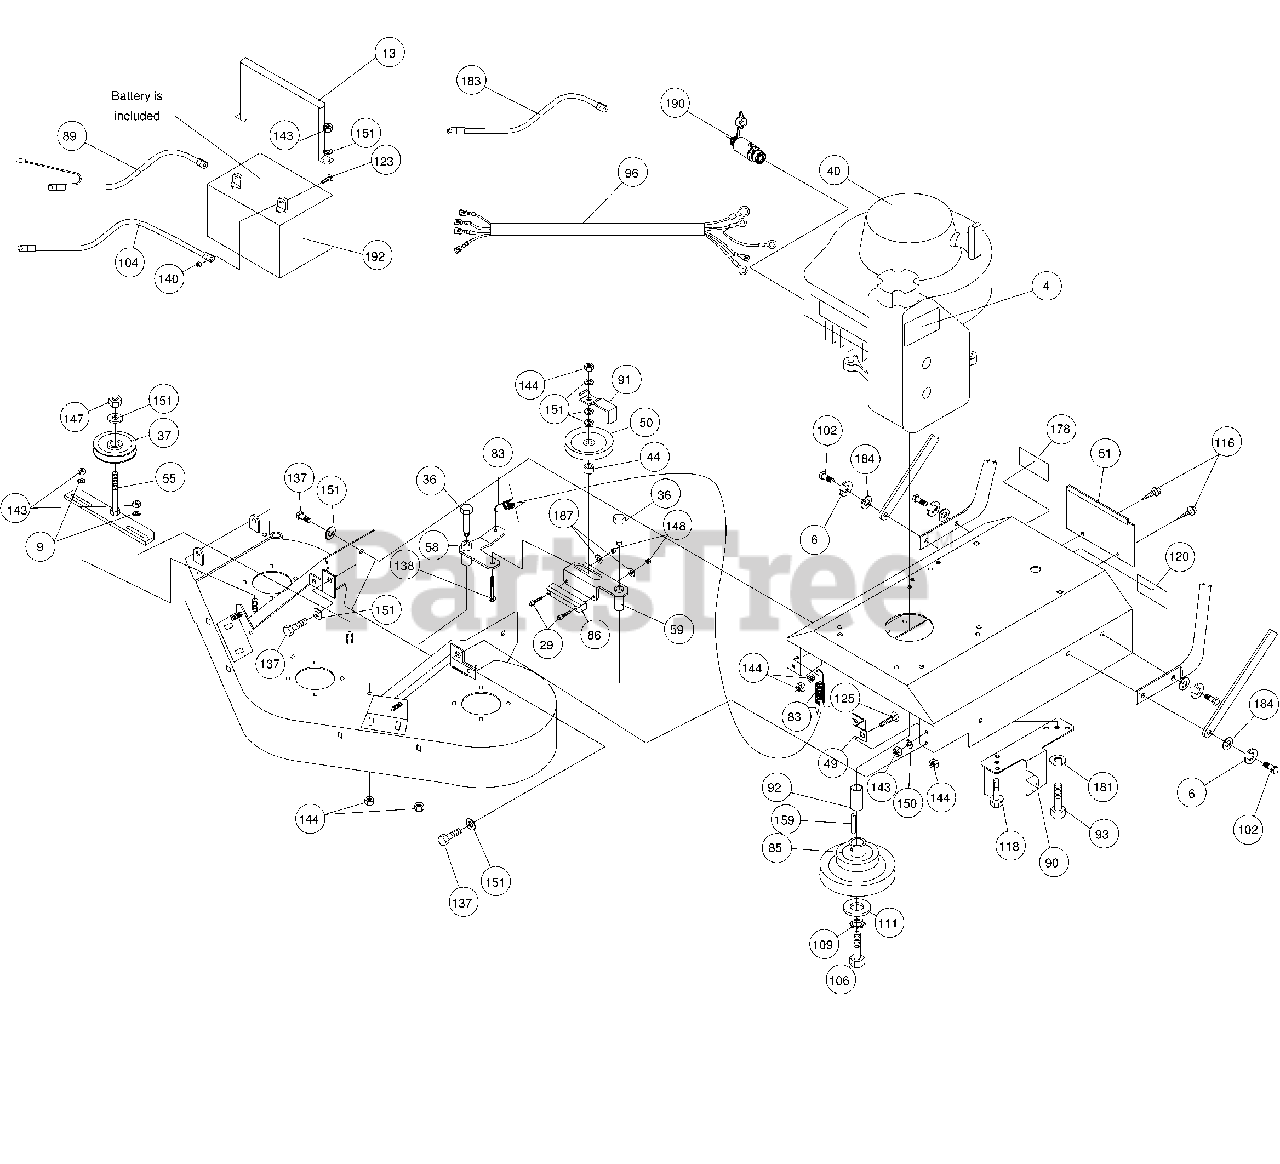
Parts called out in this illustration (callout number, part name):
4	LABEL HOT ENGINE
6	WASHER SPLIT LOCK 3/8"
9	WASHER 5/16" TWISTED LK.
13	BATTERY BRACKET
29	SCREW SOCKET #10 X 1”
36	BOLT SHOULDER 1/2” X 2”
37	IDLER PLASTIC 4” X 0.375
40	ENGINE 13 HP B&S
44	SPACER NYLON BRAKE
49	BRKT CLUTCH CABLE FM
50	PULLEY IDLER BLADE DRIVE
51	PLATE ACCESS DOOR FM
55	BRKT IDLER DECK BLADE WA
58	PLATE BLADE CLUTCH IDL.
59	PLATE BLADE CLUTCH BK
83	SPRING TENSION WIRE
85	PULLEY DOUBLE 6 / 3.5 FM
86	BRAKE PUCK FM
89	CABLE BATTERY POS 10”
90	BRACKET BELT FINGER
91	BRACKET BELT FINGER BK.
92	SPACER HUB 1” BORE 1.5”
93	SCREWCAP 5/16” -18 x 2"
96	WIRE HARNESS
102	SCREWCAP 3/8” - 1.25”
104	CABLE BATTERY BLACK 10”
106	SCREWCAP 7/16 X 2 1/4 GR 8
109	WASHER LOCK 7/16 TWIST
111	WASHER ENGINE PULLEY
116	SCREW 1/4” - 20 X 5/8"
118	SCREWCAP 3/8” 1 1/2" TAP
120	LABEL GUARDS
123	BOLT CARRIAGE 1/4" X 3/4"
125	BOLT CARRIAGE 5/16" X 1"
137	SCREW CAP 3/8"-16 X 1 HEX
138	SCREW CAP 3/8"-16 X 2 HEX
140	NUT LOCK 1/4"-20 NYLON
143	NUT LOCK 5/16"-18 NYLON
144	NUT LOCK 3/8"-16 NYLON
147	NUTLOCK 3/8"-16 LW TH ZP
148	NUT LOCK #10
150	WASHER 1/4” FC
151	WASHER 5/16” FC
159	KEY 1/4” SQ. X 2.25" LONG
178	LABEL DESIGN PATENT FM
181	WASHER SPLIT LOCK 5/16"
182	NUT JAM 5/16"
183	POSITIVE CABLE 10"
184	WASHER 3/8" FLATCUT
187	WASHER #10 FLATCUT
190	VALVE OIL DRAIN
192	BATTERY 12v W/LABEL
